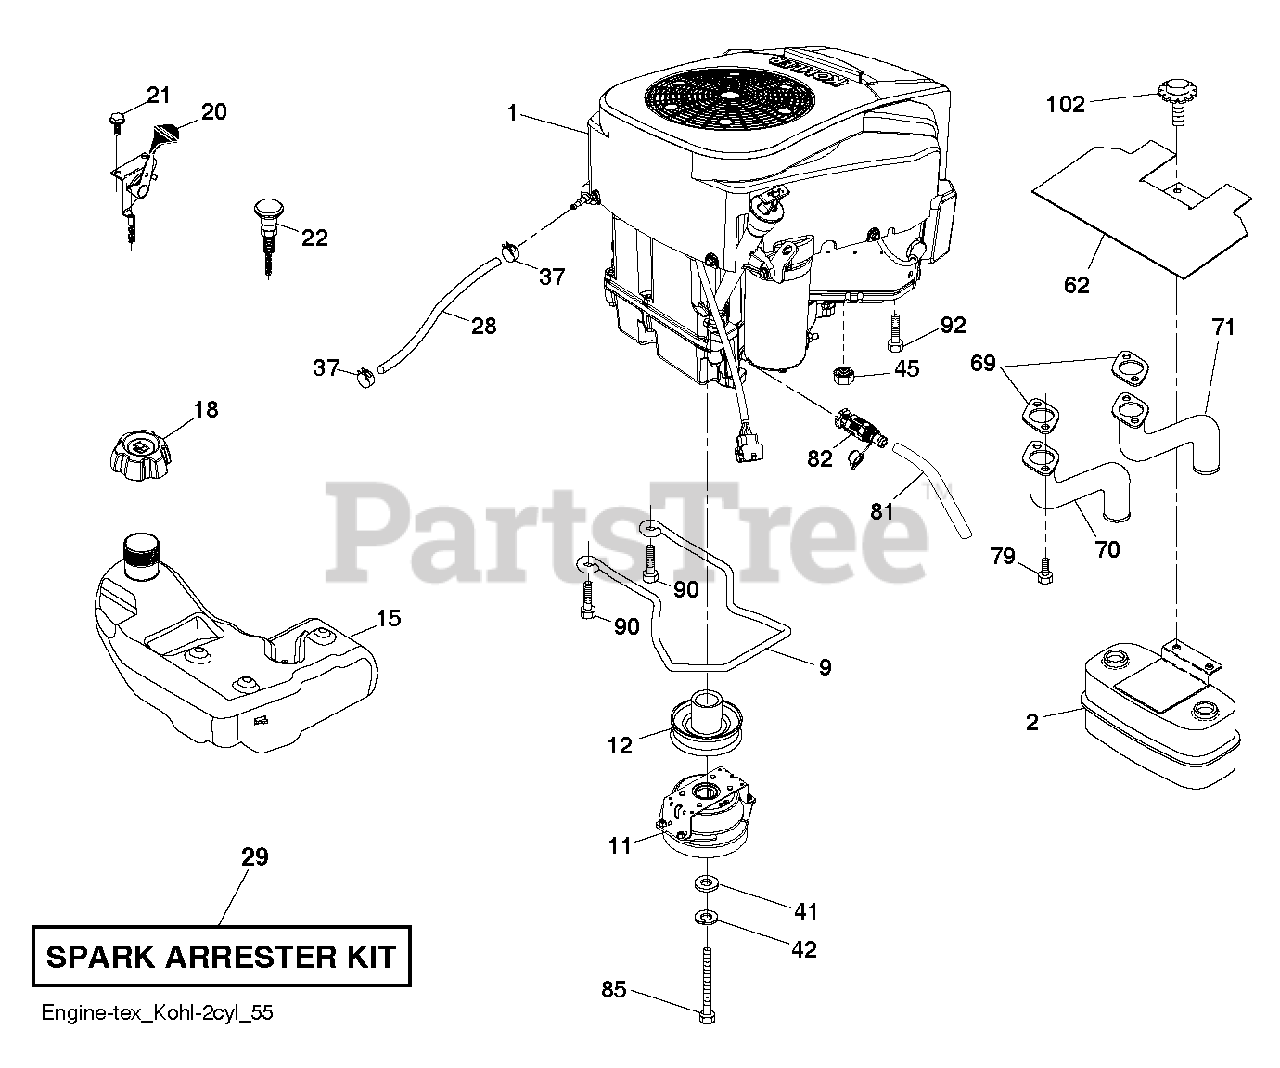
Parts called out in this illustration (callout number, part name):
2	MUFFLER.ASM.TWN.EXTNDED.DFLCTR
9	KEEPER.BELT.ENG.4.25"2.BLT.431
11	CLUTCH.OGURA.5.0PD.GT1.5A-EH07
12	PULLEY.ENGINE.TUFFTORQ
15	TANK.ASSY.3.GAL.EPA
18	CAP ASSY FUEL 3" GRAY
20	THROTTLE CONTROL
21	SCREW.#10 X 0.750.BOS
22	CONTROL.CHOKE.ERGO.PUSH-IN.BLA
28	LINE.FUEL.64"REAR.EMIS
29	KIT.SPARK ARRESTOR 794945 B&S
37	HOSE CLAMP
42	LOCKWASHER
45	NUT
62	SHIELD.HEAT.MUFFLER
69	GASKET.EXHAUST.KOHL.CV18-CV26
70	PIPE.EXHAUST.LH.CV18/20
71	PIPE.EXHAUST.RH.CV18/20
79	SCREW.SOCKET HD.5/16-1
81	TUBE, DRAIN OIL ASM.
82	VALUE.OIL.DRAIN
85	BOLT HEX 7/16-20 X 3.75 GR. 5
90	SCREW 3/8-16X1
92	SCREW 3/8-16X1
102	SCREW
